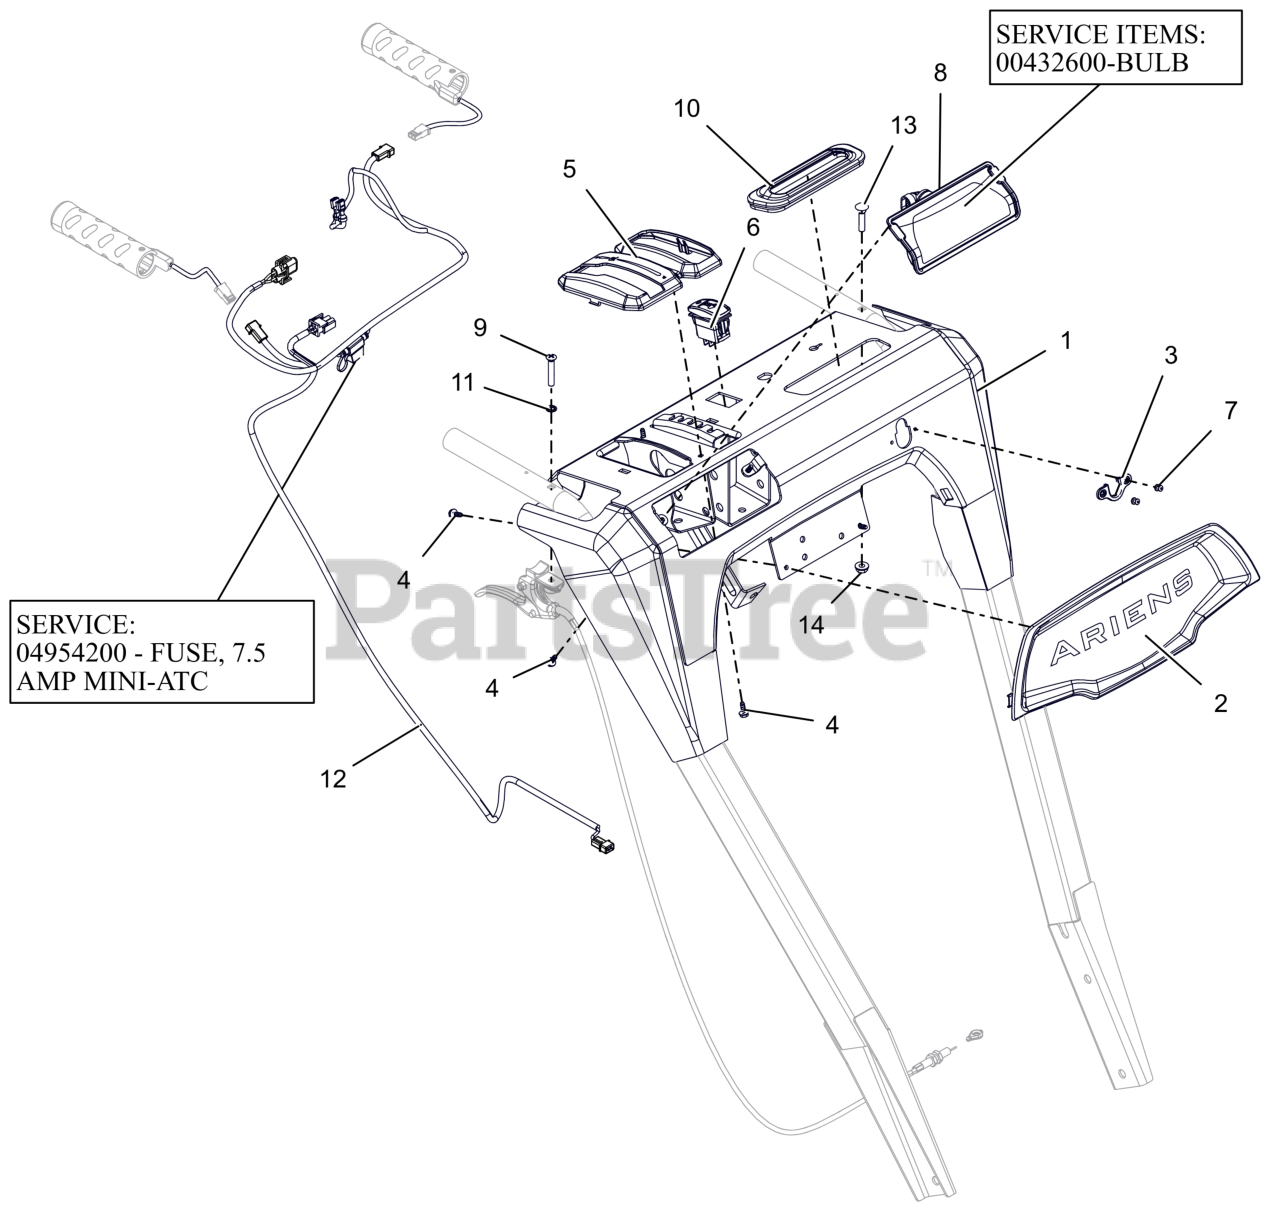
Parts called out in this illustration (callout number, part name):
1	PANEL, DASH-HYDRO EFI W/DECAL
2	BEZEL, DASH - ARIENS LG DASH
3	GROMMET, CABLE, QUICK TURN 2
4	SCR, PLASTIC #10X.50
5	BEZEL, SHIFT - HYDRO SNOW
6	SWITCH,ROCKER SPST-ON/OFF
7	RVT-POP #43 .125X.313 STL ZINC
8	HEADLIGHT ASY, HALO 20W 2SHOT
8	BULB, LIGHT-HALOGEN 20W
9	SCR,OVAL .25-20X1.50 ZCC
10	GROMMET, BOOT, QUICK TURN
11	WSHR-LK-INT .250 TH TYA
12	HARNESS,LIGHT&WARMER - EFI
12	FUSE, 7.5 AMP MINI-ATC
13	BLT-RDHDXLSQNK.25-20X1.25 G5ZC
14	NUT-LK-CTR-FLG .25-20 ZC120
